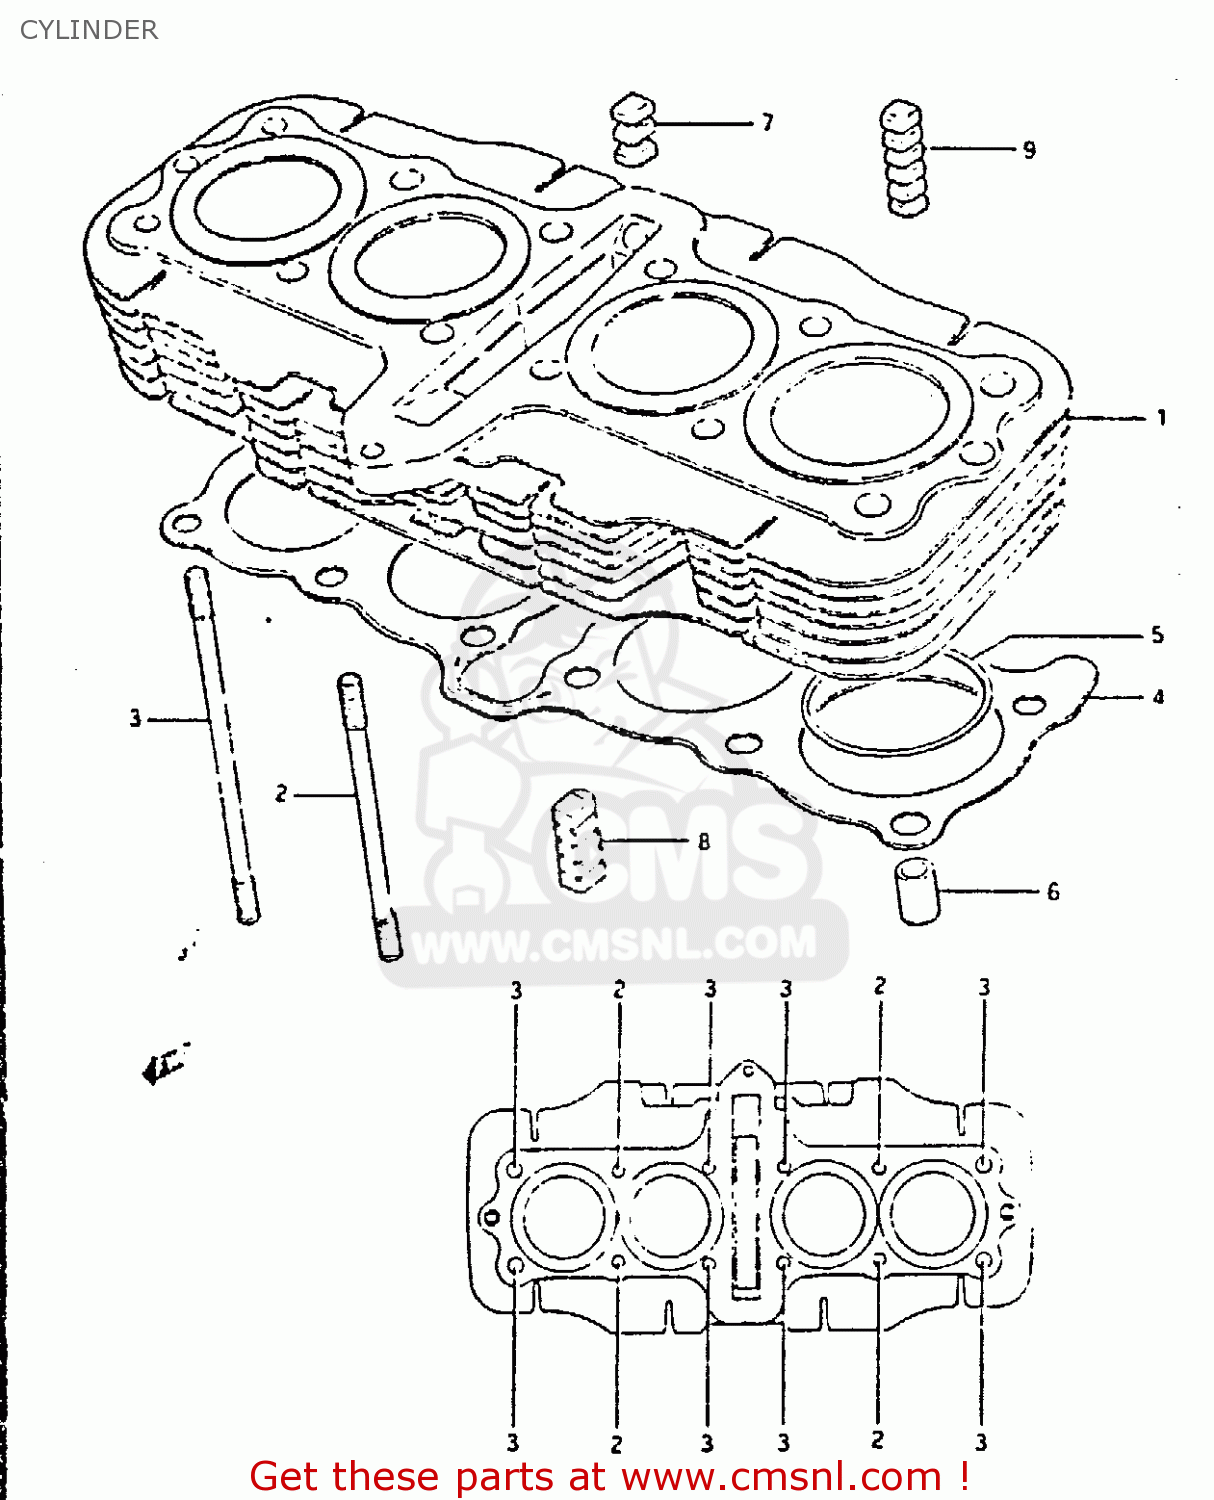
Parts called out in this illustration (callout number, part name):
1	CYLINDER
2	BOLT,STUD
3	BOLT,STUD
4	GASKET,CYLINDER (MCA)
5	O RING(D:2,ID:61)
6	PIN
7	PIN,EXHAUST VALVE
8	PIN,EXHAUST VALVE
9	PIN,EXHAUST VALVE
